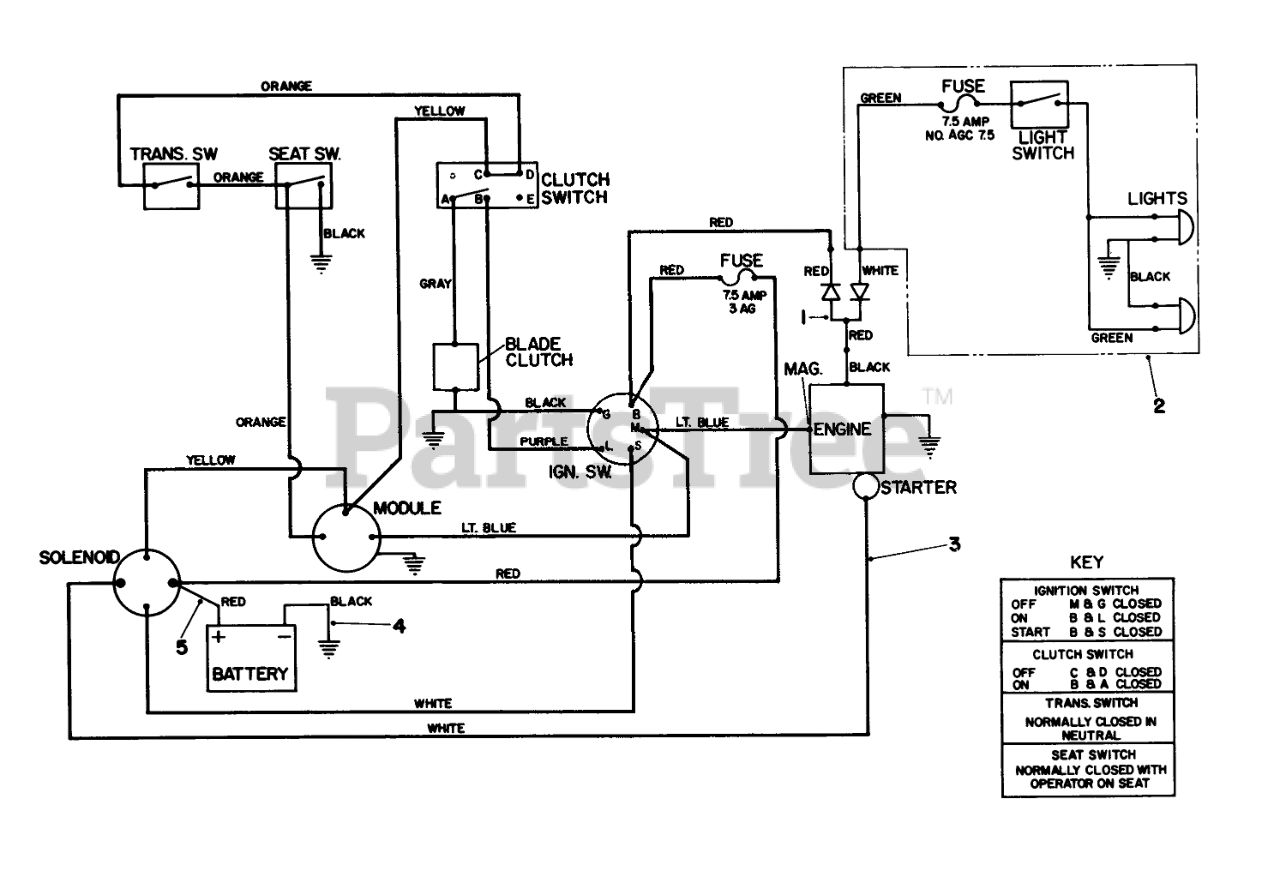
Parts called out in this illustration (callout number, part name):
1	WIRE HARNESS WIRE
2	WIRE HARNESS
3	WIRE HARNESS
4	WIRE ASM
5	WIRE ASM
